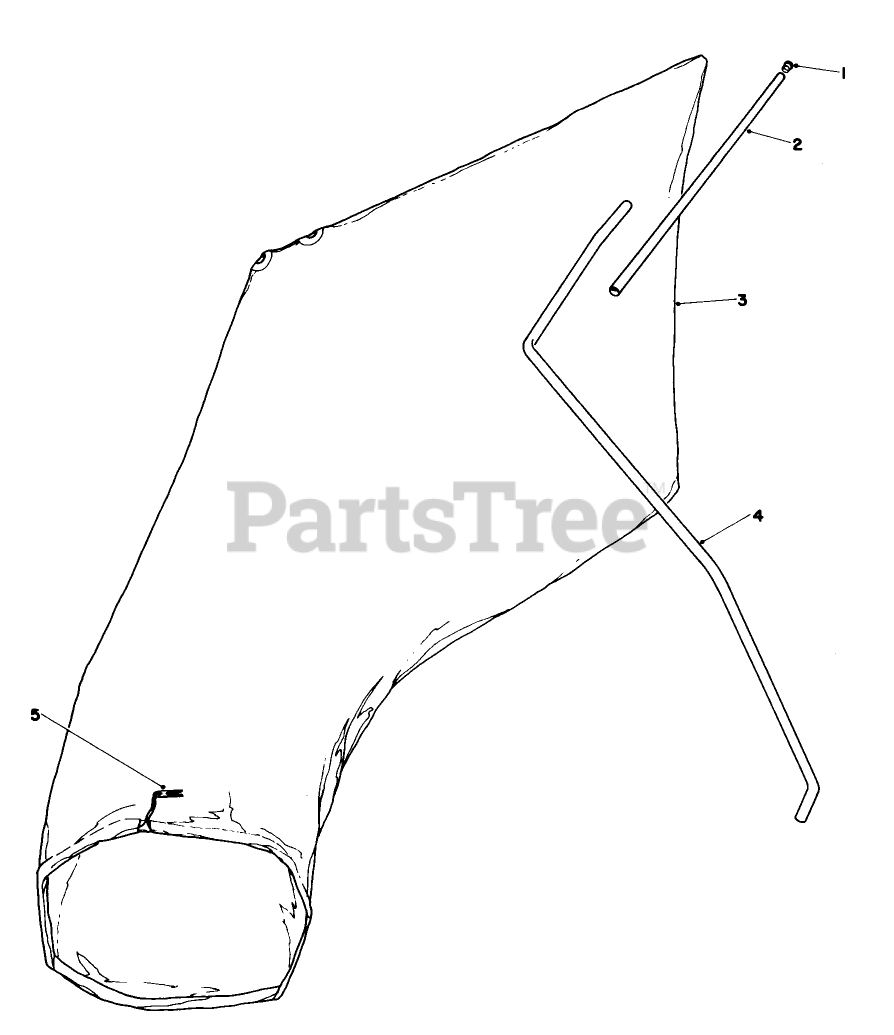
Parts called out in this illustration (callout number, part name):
2	BAG HANGER TUBE
3	Bag (Incl. Ref. #5)
4	HANGER ROD
5	BAG CORD FASTENER
